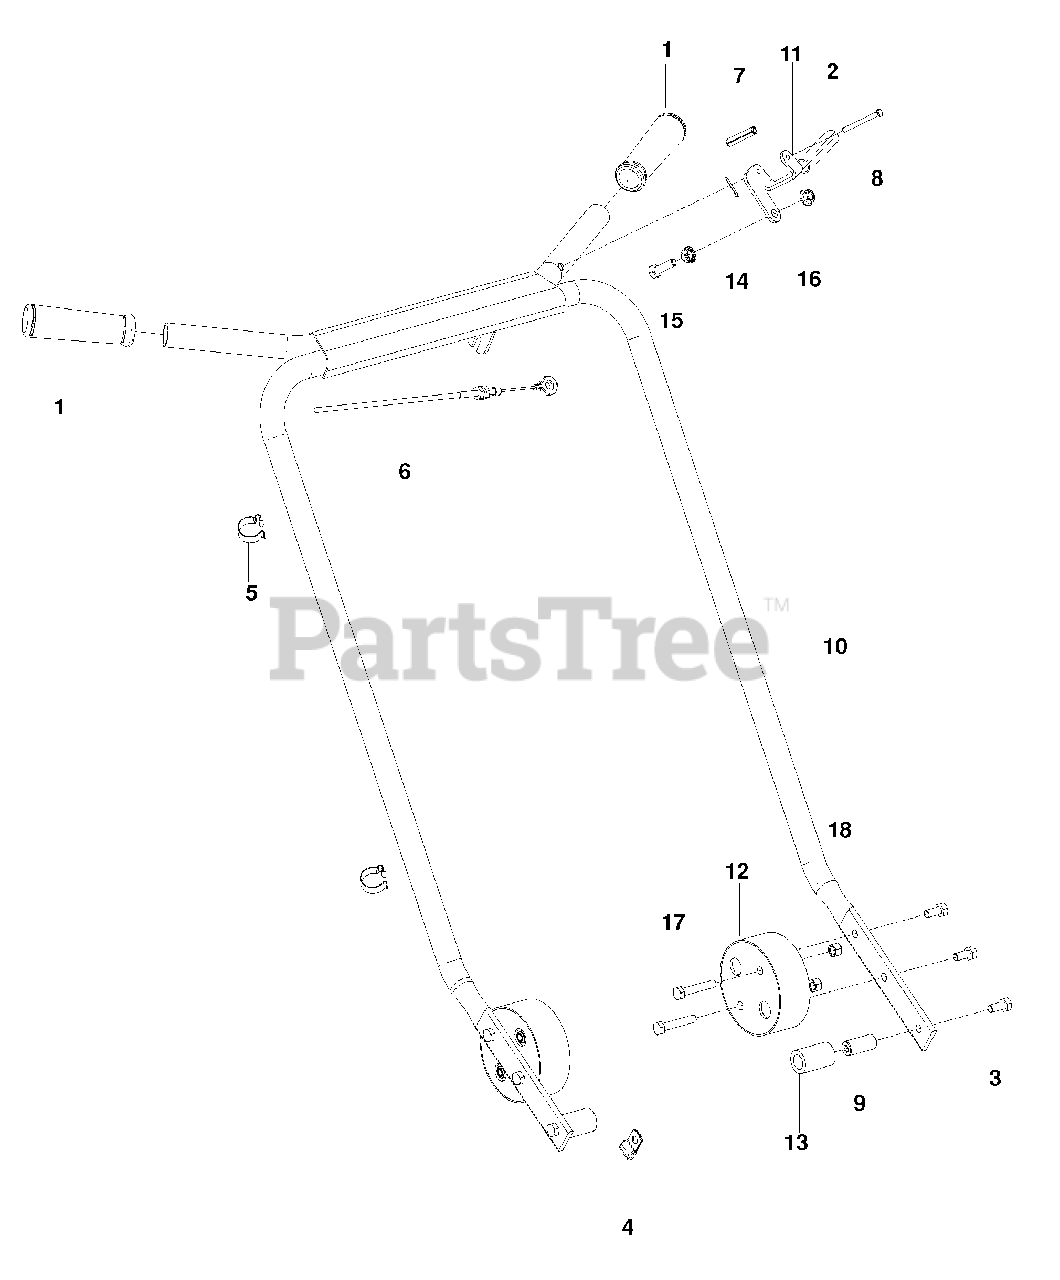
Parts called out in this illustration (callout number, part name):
1	GRIP, HANDLE
2	GRIP, VINYL
3	HCS, M8-1.25 x 22MM, GR8.8
4	TUBE CLAMP, DOUBLE
5	CLIP, CABLE
6	CABLE PULL
7	ROLL PIN 5/16 x 1 1/2
8	PIN, CLEVIS
10	HANDLE GRY
11	LEVER, THROTTLE
14	PIN COTTER 3/32 x 3/4
15	HCS 5/16-18 x 1
16	NUT 5/16-18 WHIZLK
17	HCS 5/16-18 x 1 3/4
18	NUT 5/16-18 NYLOC
